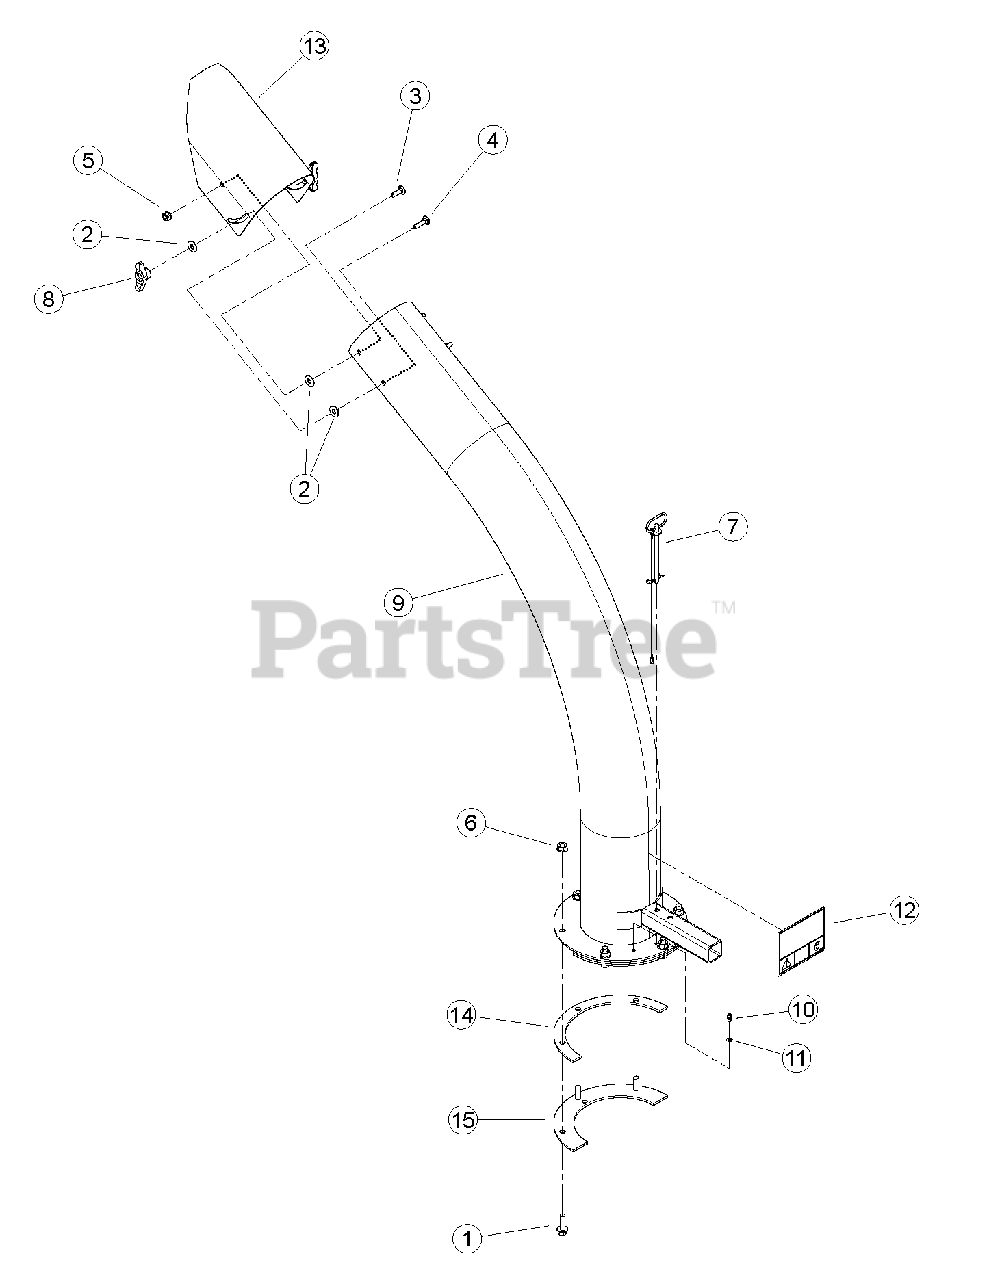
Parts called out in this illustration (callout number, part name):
1	BOLT, 3/8 X 1-1/4 FLANGE NC
2	WASHER, 5/16" FLAT ZP
3	BOLT, 5/16" X 1" GR5 CRG ZP
4	BOLT, 5/16 X 1-1/4" GR5 ZP CRG
5	NUT, 5/16-18 NYLOCK-FLANGE
6	NUT, 3/8-16 NYLOCK FLANGE
7	PIN, 3/8" X 4.25" DISCHARGE
8	KNOB, 5/16-18 UNC TEE W/LOCKING INSERT
9	ASSEMBLY, 6 INCH DISCHARGE CHUTE
10	FITTING, 1/4 SELF-TAP GREASE
11	WASHER, FLAT .254 X .400 X .048
12	DECAL, DISCHARGE DEBRIS & LOCK
13	DEFLECTOR, BLOWER VAC DISCHARGE
14	SPACER, DISCHARGE PIVOT
15	RING, DISCHARGE CLAMP
